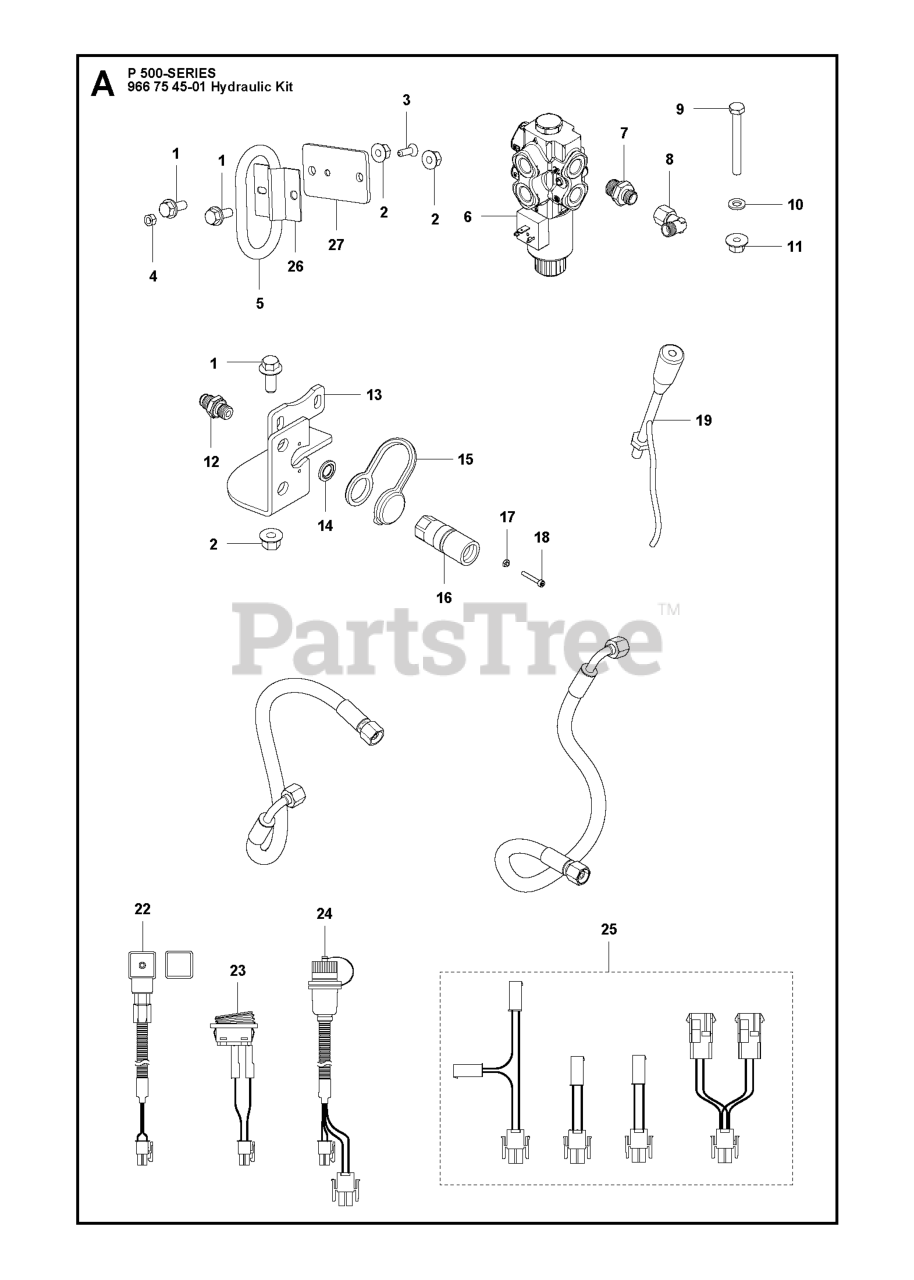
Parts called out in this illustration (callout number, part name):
2	NUT FLANGE
9	SCREW M6X55
10	WASHER - M6
11	NUT FLANGE
17	NUT M6M M3
